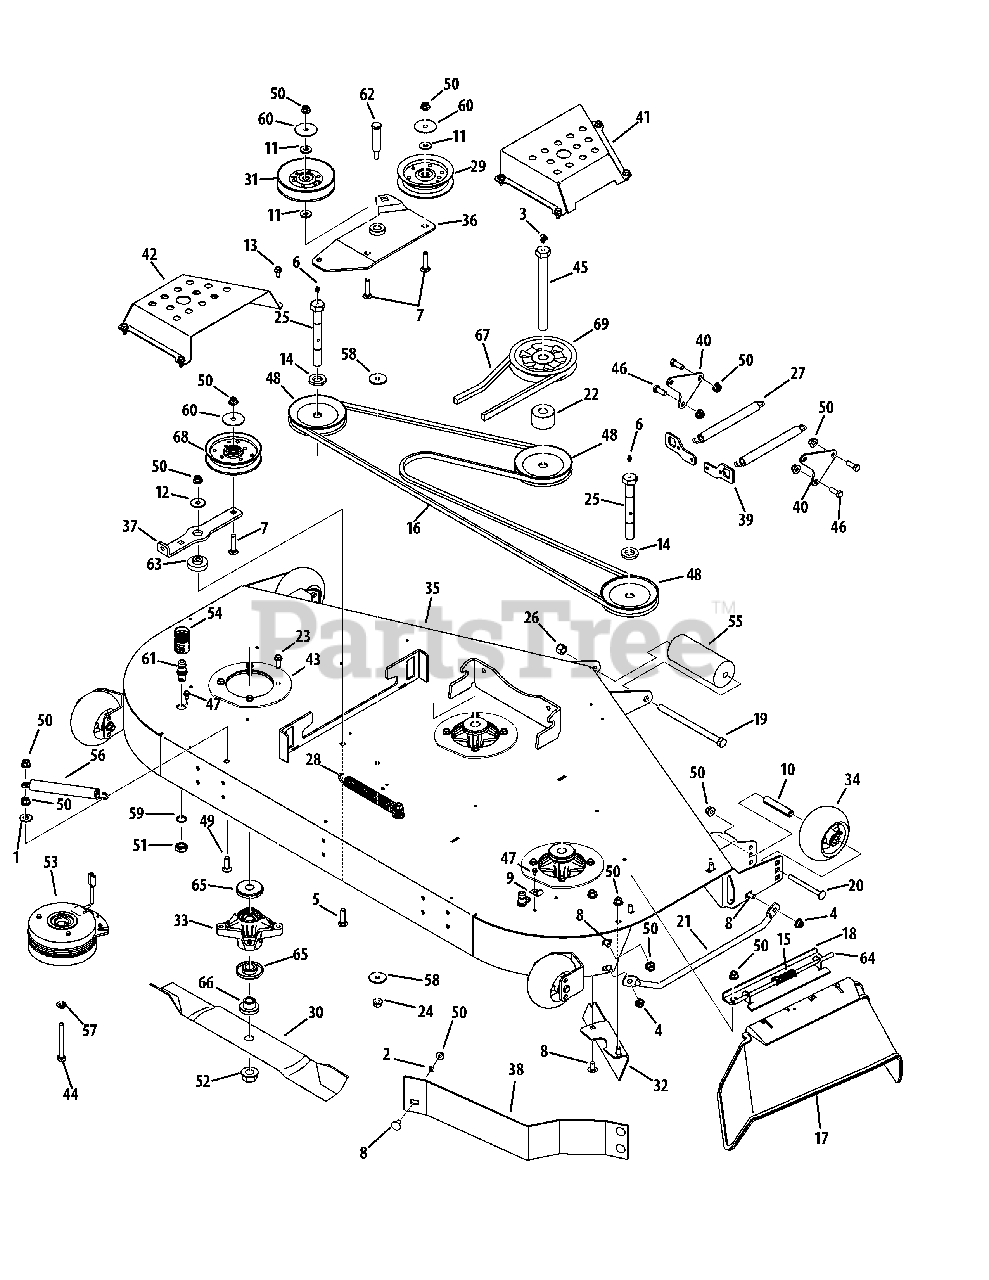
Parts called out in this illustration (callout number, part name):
1	Washer, .532 x 1.06 x .094
2	Retainer Nut
3	Grease Fitting, 1/4-28 x .788
4	Counterlock Flange Nut, 3/8-16
5	Carriage Bolt, 3/8-16 x 1.50
6	Straight Grease Fitting, 1/4-28
7	Carriage Bolt, 3/8-18 x 1.75
8	Carriage Bolt, 3/8-16 x .75
9	Retainer Hook
10	Spacer, .390 x .620 x 3.04
11	Washer, .406 x 1.00 x .105
12	Washer, .411 x 1.25 x 1.00
13	TT Screw, 5/16-18 x .750
14	Spacer, .812 x 1.47 x .218
15	Torsion Spring
16	V- Belt
17	Fab Deck Deflector Chute
18	Deflector Chute Bracket
19	Hex Screw, 1/2-20 x 7.50
20	Carriage Bolt, 3/8-16 x 4.00
21	Fab Deck Chute Finger Guard
22	Spacer, .760 x 2.00 x 1.69
23	Flange Hex TT Screw, 5/16-18 x 1.50
24	Nut, Hexlk, 1/2-20, Gr2, Nylon
25	Hex Screw, 3/4-16 x 6.00
26	Nylock Nut, 1/2-20
27	Hook Ext. Spring, .75 x 7.89 x .14
28	Hook Ext. Spring, .94 x 7.57 x .14
29	Idler Pulley, 4.88
30	Hi-Lift Blade, 21.0
31	Idler Pulley, 5.06
32	Deck Chute Baffle
33	Deck Spindle Assembly
34	Deck Wheel
35	60" Welded Deck
36	60" Idler Assembly
37	Deck Idler Arm
38	Standard Baffle
39	Spring Mount Bracket
40	Spring Mount Plate
41	60" RH Belt Cover
42	60" LH Belt Cover
43	Spindle Reinforcement Plate
44	Hex Screw, 7/16-20 x 3.50
45	Hex Screw, 3/4-16 x 8.0
46	Hex Screw, 3/8-16 x 1.00
47	Hex Washer TT Screw, 1/4-20 x .500
48	V-Type Pulley
49	Carriage Bolt, 3/8-16 x 1.25
50	Flange Lock Nut, 3/8-16
51	Hex Nut, M16-1.5
52	Flange Lock Nut, 3/4-16
53	Electric PTO Clutch
54	Water Nozzle Adapter
55	Front Roller
56	Extension Spring, .91 x 7.33
57	Lock Washer, 7/16
58	Flat Washer, .390 x 1.500 x .134
59	Lock Washer, 17 x 23.8 x 1.95
60	Flat Washer, .406 x 1.92 x .060
61	Water Deck Nozzle
62	Shoulder Bolt, 3/8-16 x .74 x 2.47
63	Shoulder Spacer, .854 x .280
64	Chute Deflector Rod
65	Deck Spindle Spacer
66	Spindle Spacer, .76 x 2.0 x 1.1
68	Idler Pulley, 4.25
69	V-Type Pulley
